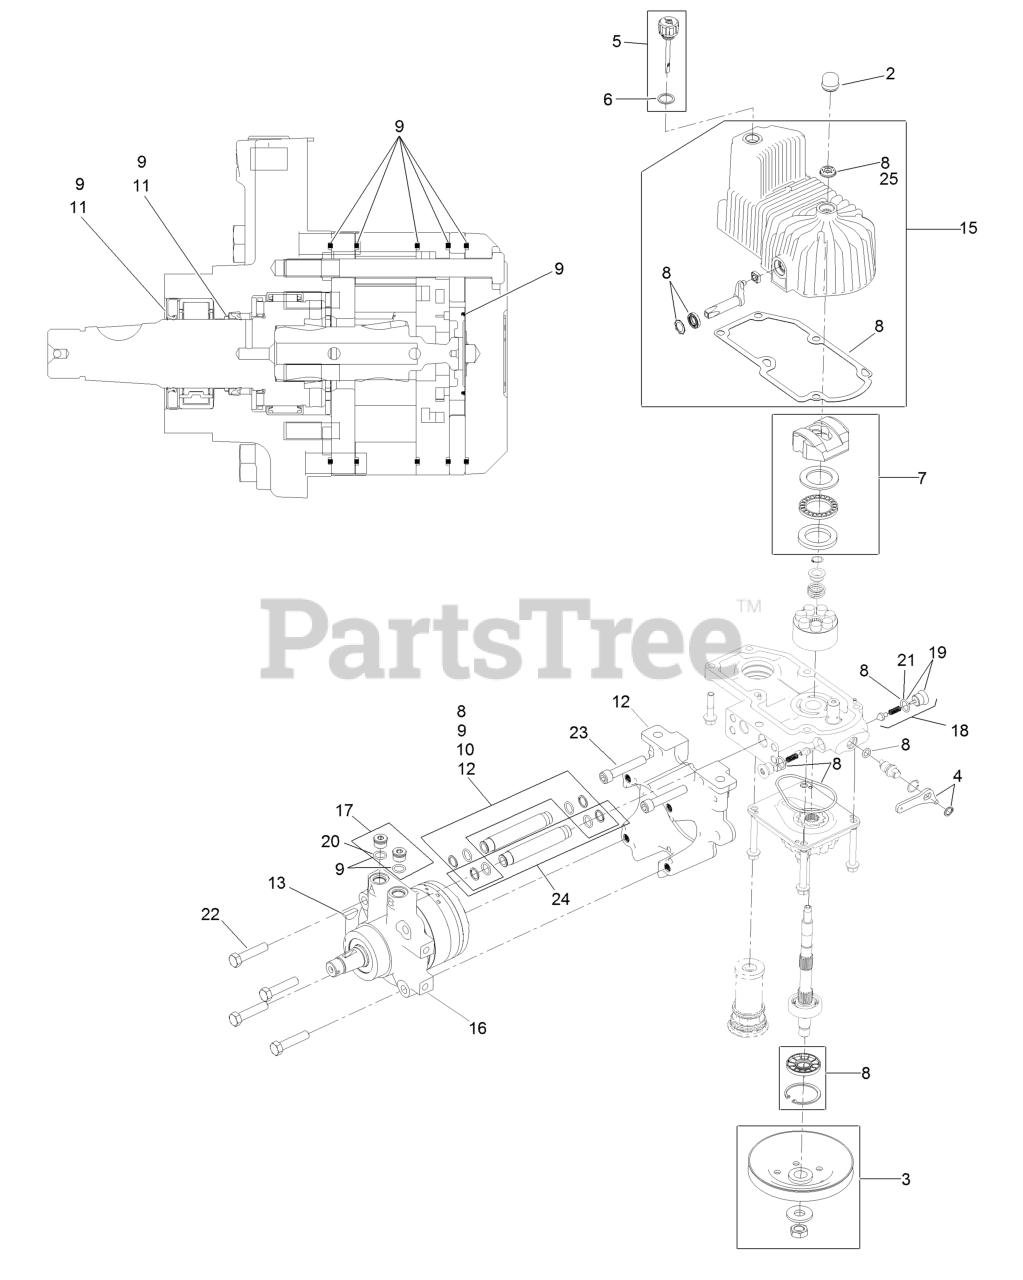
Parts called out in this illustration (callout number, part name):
2	Cover-Shaft, Hydro
3	Pulley Kit
4	Handle-Bypass Valve, Hydro
5	Dipstick-Hydro W/Gasket
6	Gasket-Dipstick, Hydro
7	Swash Block Kit
8	Pump Seal Kit
9	Motor Seal Kit
10	Tube Seal Kit
11	Output Shaft Seal Kit
12	Nose Cup-Uht
13	Key-Woodruff
15	Housing-LH
16	Motor-Hydraulic LH 240Cc
17	Magnetic Plugs Service Kit
18	Check Valve ASM
19	Plug-Check (W/O-Ring)
21	O-Ring-Check Valve
22	Screw HH
23	Screw-HSH
24	Hydraulic Tube Kit
25	Seal-Fan Drive
99	Puller-Pulley
99	Flow Test Kit
